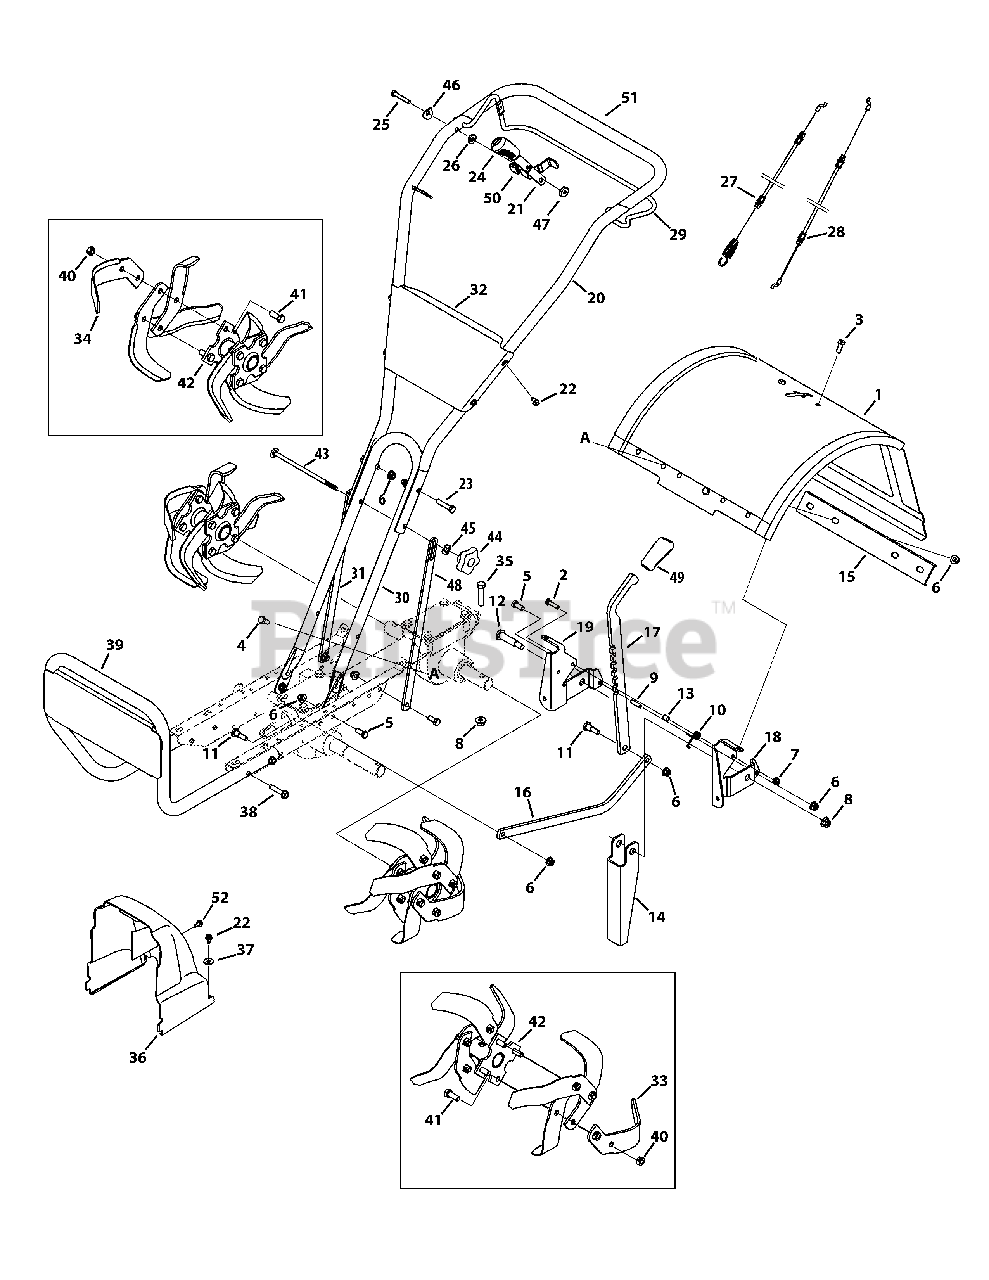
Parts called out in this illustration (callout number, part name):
1	Tine Shield Assembly
2	Hex Head Screw, 1/4-20 x 1.00
3	Screw, 5/16-18 x 0.625
4	Hex Head Washer, 5/16-18 x .875
5	Hex Head Screw, 5/16-18 x .75
6	Flangelock Nut, 5/16-18
7	Flangelock Nut, 1/4-20
8	Flangelock Nut, 3/8-16
9	Spring Pin, 1/4 DIA x 1.00 LG
10	Torsion Spring
11	Screw, Shoulder, 5/16-18 x .405 x .435
12	Screw, Shoulder, $r .498 x 1.635
13	Spacer, Split, .350 x .268 x .375
14	Stop Reverse Arm
15	Support Channel Bracket
16	Depth Drag Bar
17	Depth Adjuster Bar
18	LH Tail Bracket
19	RH Tail Bracket
20	Upper Handle Assembly
21	Reverse Handle Assembly
22	Screw, 1/4-20 x 0.500
23	Hex Head Screw, 5/16-18 x 1.50
24	Reverse Handle Grip
25	Hex Head Screw, 1/4-20 x 1.62
26	Flat Washer, .265 x .938 x .120
27	Forward Cable
28	Reverse Cable
29	Clutch Bail
31	Support Handle Bracket
33	RH Bolo Tine
34	LH Bolo Tine
35	Hex Head Screw, 3/8-16 x 1.75
36	Belt Cover
37	Washer, Flat, .28 x .74 x .063
38	Screw, 5/16-18 x 1.50
39	Bumper
40	Nut, Hexlock, 3/8-16
41	Hex Head Screw, 3/8-16 x 1.00
42	Tine Holder Assembly
43	Tine Holder Assembly
44	Carriage Bolt, 5/16-18 x 6.75
45	Knob, 5/16-18
46	Washer, .326 x .875 x .145
47	Washer, Saddle, .320 x .93 x .060
48	Spacer, .375 x .165
49	Support Handle Bracket
49	Handle Grip
50	Reverse Handle Grip
51	Handle Grip
52	Self Tapping Screw, 1/4-14 x .625
